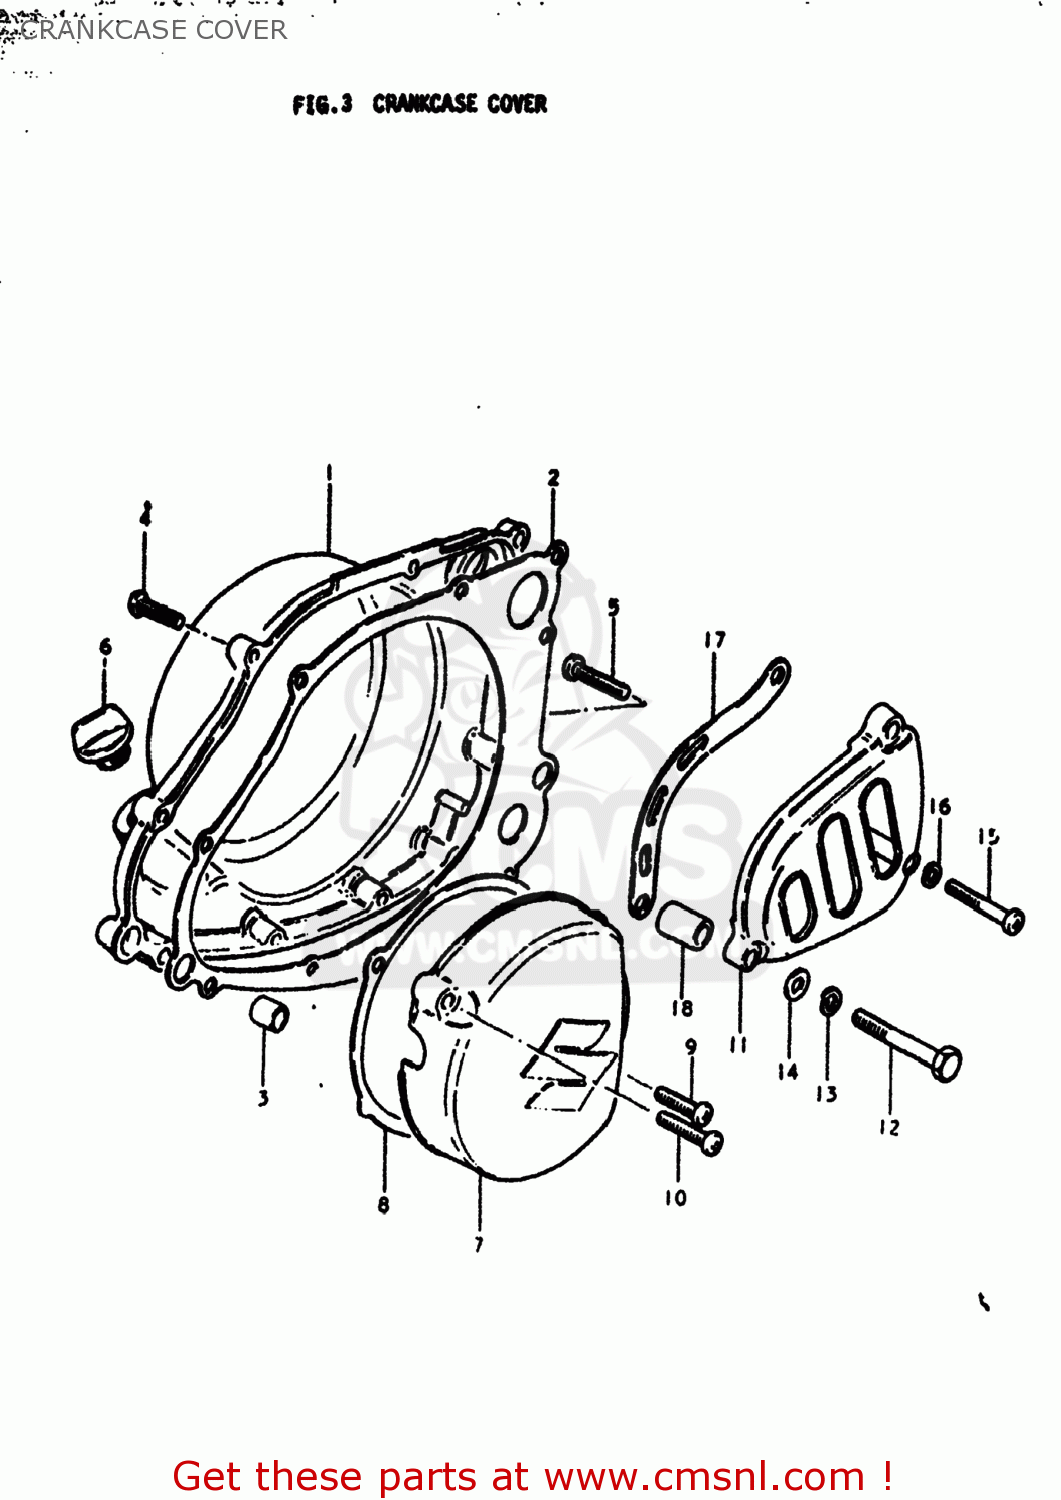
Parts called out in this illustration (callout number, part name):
1	COVER,CLUTCH
2	GASKET,CLUTCH COVER (MCA)
3	PIN
4	SCREW
5	SCREW (6X45)
6	PLUG,OIL FILTER
7	COVER
8	GASKET,MAGNETO COVER (MCA)
9	SCREW
10	SCREW
11	COVER,SPROCKET
12	BOLT 8X55
13	LOCK WASHER
14	WASHER
15	SCREW
16	LOCK WASHER
17	PLATE,FR CHAIN GUIDE
18	SPACER(8.6X16X24)
